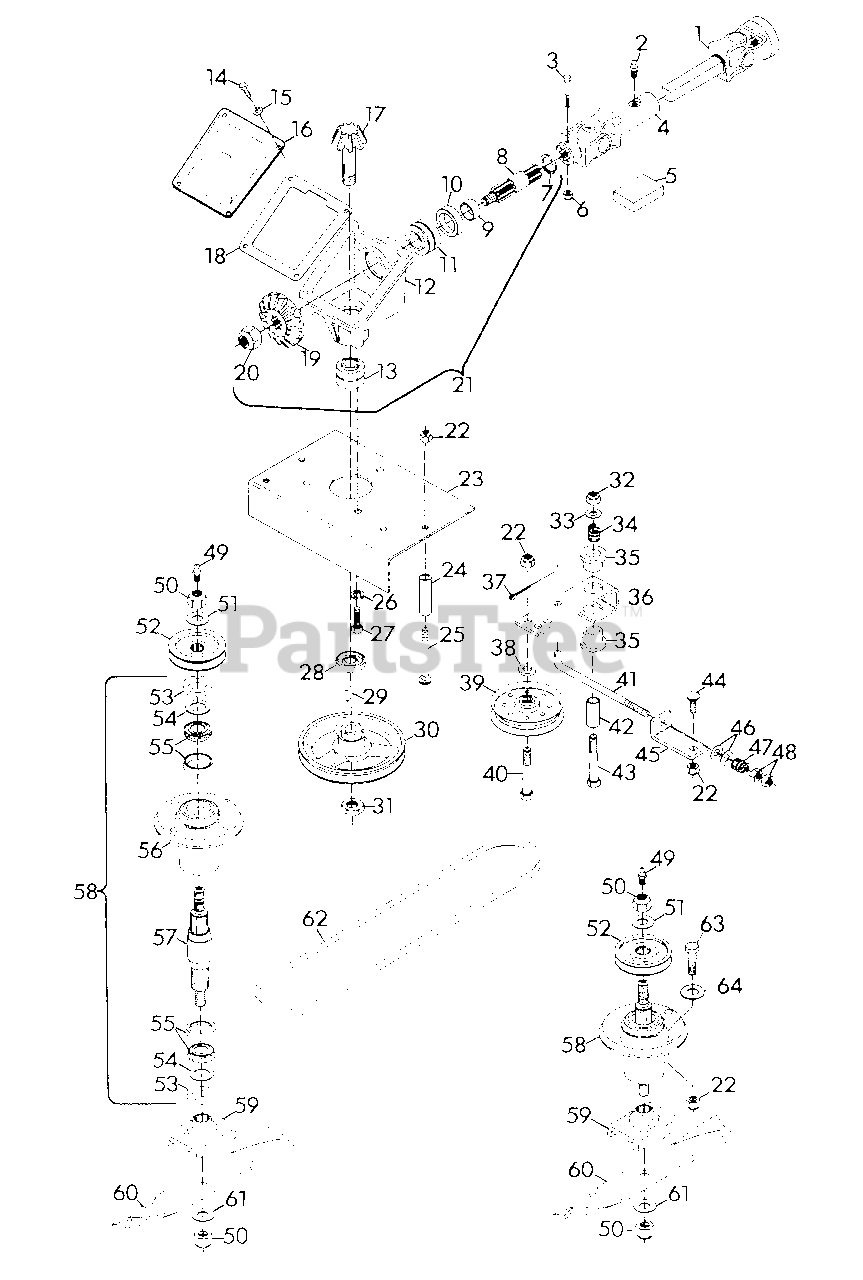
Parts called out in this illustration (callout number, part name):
1	SHAFT, PROP. SQ. BAR
2	FITTING, LUBE 1/4-28
3	BOLT, HEX 1/4-20X2
4	U-JOINT, FEMALE END
5	KIT, REPAIR U-JOINT(NEAPCO)
6	NUT, LOCK 1/4-20
7	RING, RETAINING 1.000 SHAFT
8	SHAFT, DRIVE
9	SPACER
10	SEAL, OIL 1.250X1.987X.250
11	ASSEMBLY, BEARING 1.000X1.980X1.243
12	CASTING, GEAR BOX
13	ASSEMBLY, BEARING .750X1.781X1.499
14	BOLT, HEX 1/4-20X.50
15	WASHER, LOCK 1/4 REG.
16	COVER, GEAR HOUSING
17	SHAFT, GEAR PINION
18	GASKET, GEAR HOUSING
19	GEAR, BEVEL
20	NUT, LOCK 3/4-10
21	ASSEMBLY, DRIVE
22	NUT, LOCK 3/8-16
23	SUPPORT, GEAR BOX
24	SPACER
25	BOLT, 3/8-16X3.50 RD HD SQ NK
26	WASHER, LOCK 1/2 REG.
27	BOLT, HEX 1/2-13X1
28	SEAL, OIL 1.250X1.686X.313
29	KEY, WOODRUFF .188X.625 HARD #61
30	SHEAVE, 1/2X6.50
31	NUT, JAM 3/4-10 HEX HEAVY
32	NUT, LOCK 1/2-13
33	WASHER, FLAT .531X1.250X.100
34	SPRING, COMPRESSION 1X.80X36 LB/N
35	BUSHING, NYLON .760X1.00X.600
36	ARM, IDLER PIVOT
37	PIN, COTTER .09X.75
38	SPACER, IDLER. 406X.750X.188
39	SHEAVE, IDLER
40	BOLT, HEX 3/8-16X2.25
41	ROD, IDLER
42	SPACER
43	BOLT, HEX 1/2-13X3.25
44	BOLT, 3/8-16X1.00 RD HD SQ NK
45	BRACKET
46	WASHER, FLAT .406X.812X.065
47	SPRING, COMPRESSION 1.00X.78
48	NUT, HEX 3/8-24
49	FITTING, LUBE 1/8 NPT
50	NUT, LOCK 5/8-11
51	WASHER, FLAT .687X1.312X.122
52	SHEAVE, SPINDLE
53	SEAL, STEEL
54	WASHER, FLAT .975X1.970X.030
55	ASSEMBLY, BEARING
56	HOUSING, BEARING
57	SHAFT, SPINDLE
58	ASSEMBLY, SPINDLE
59	WELDMENT, BLADE CRADLE
60	BLADE, 36" MOWER
61	WASHER, FLAT .656X1.312X.095
62	BELT, 36" MOWER
63	BOLT, HEX 3/8-16X1.250
64	WASHER, FLAT .438X1.00X.083
